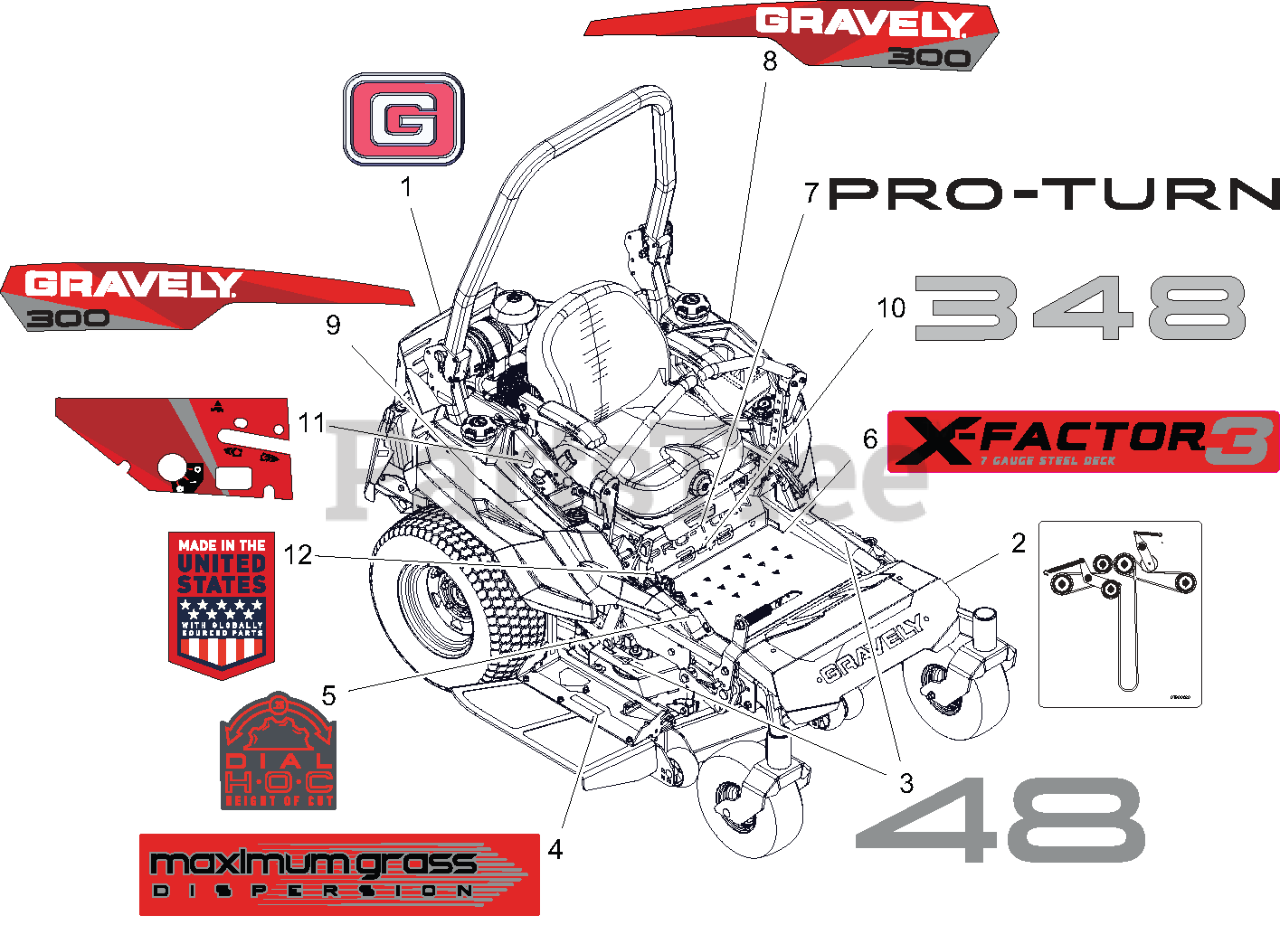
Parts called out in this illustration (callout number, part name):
1	DECAL, GRAVELY BRAND
2	DCL,BELT ROUTE-RH BK-SIDE IDLR
3	DECAL, DECK - 48
4	DECAL, DECK - MAX GRASS
5	DECAL, COVER - HOC
6	DECAL, DECK - X-FACTOR 3
7	DECAL, PRO TURN
8	DECAL- GRAVELY TANK - LH PT300
9	DECAL- GRAVLEY TANK - RH PT300
10	DECAL-348
11	DECAL- CONTROL PANEL
12	DECAL- MADE IN USA
